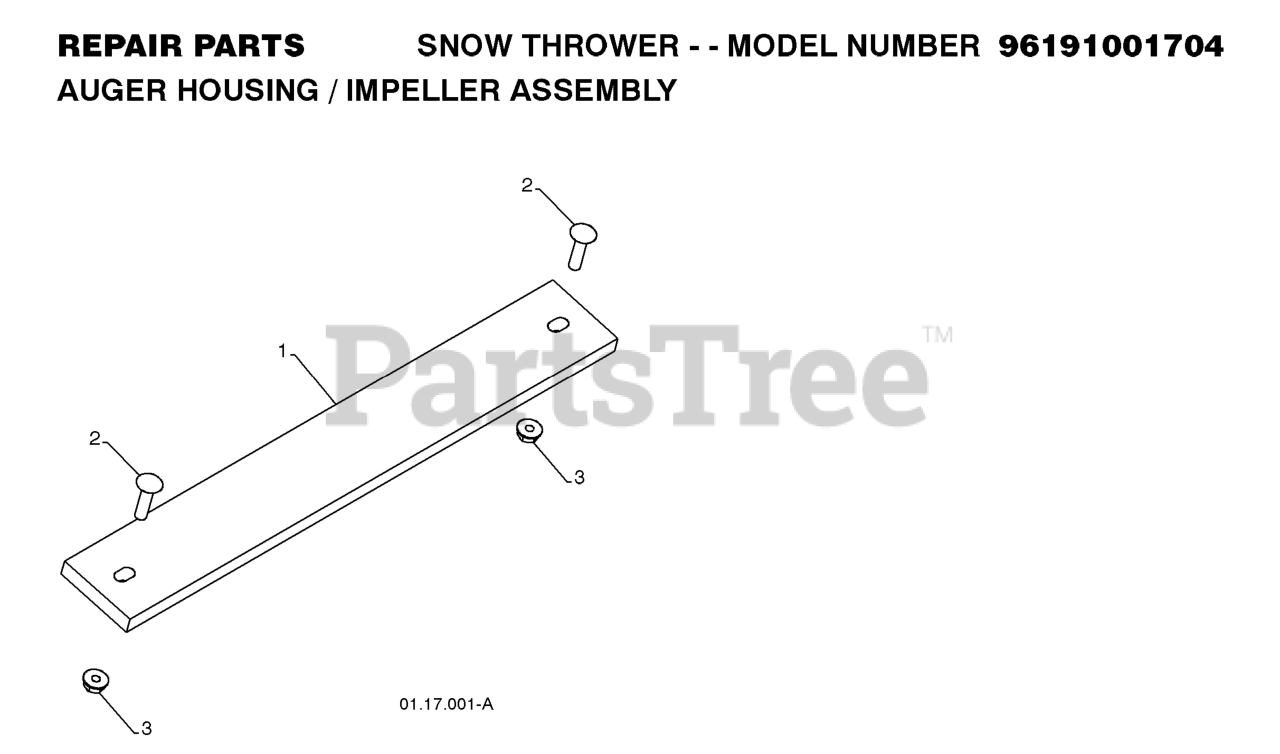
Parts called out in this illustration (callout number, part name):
1	WEIGHT.AUGER.HSG.24
2	BOLT.CARRIAGE.5/16-18
3	NUT.LOCK.5/16-18
